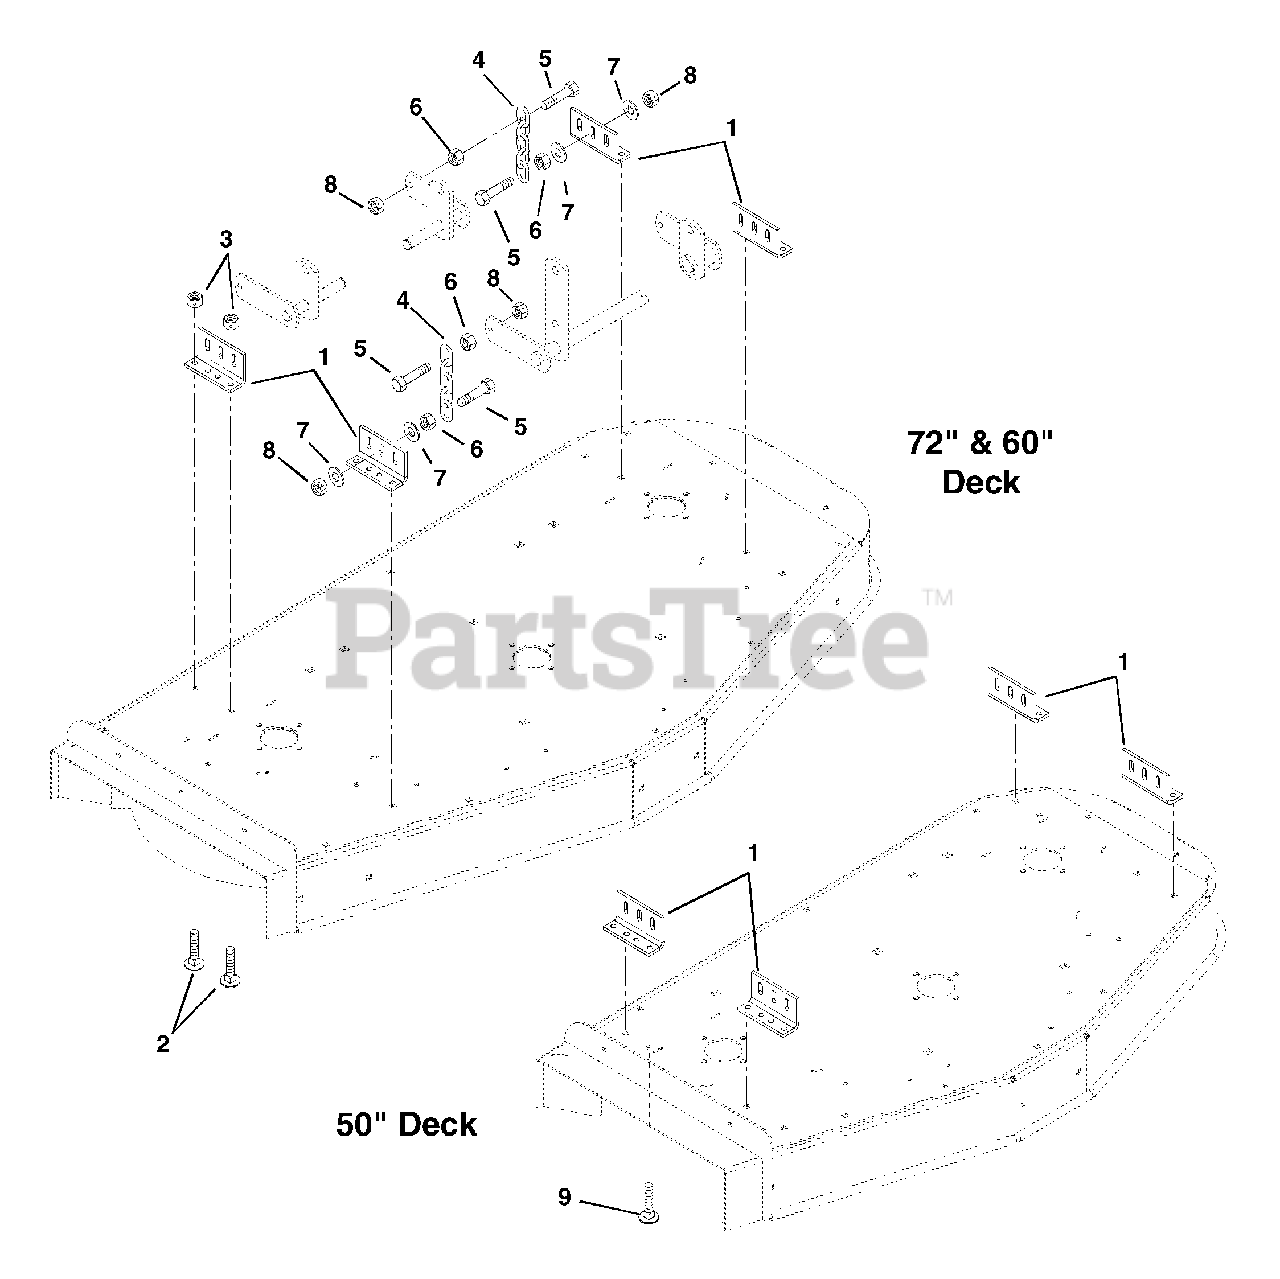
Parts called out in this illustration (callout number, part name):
1	Bracket, Mower Mounting
2	Bolt-Round Head Square Neck .38-16 x 1.25 Grade 2
3	Nut-Locking-Nylon .38 - 16
4	Chain, Link
5	Bolt-Hex .38 - 16 x 1.50 Grade 5
6	Nut-Hex .38 - 16
7	Washer-Flat-Steel .406 x .812 x .065
8	Nut-Locking-Center .38 - 16
9	Bolt-Round Head Square Neck .38 - 16 x 1.50 Grade 2
